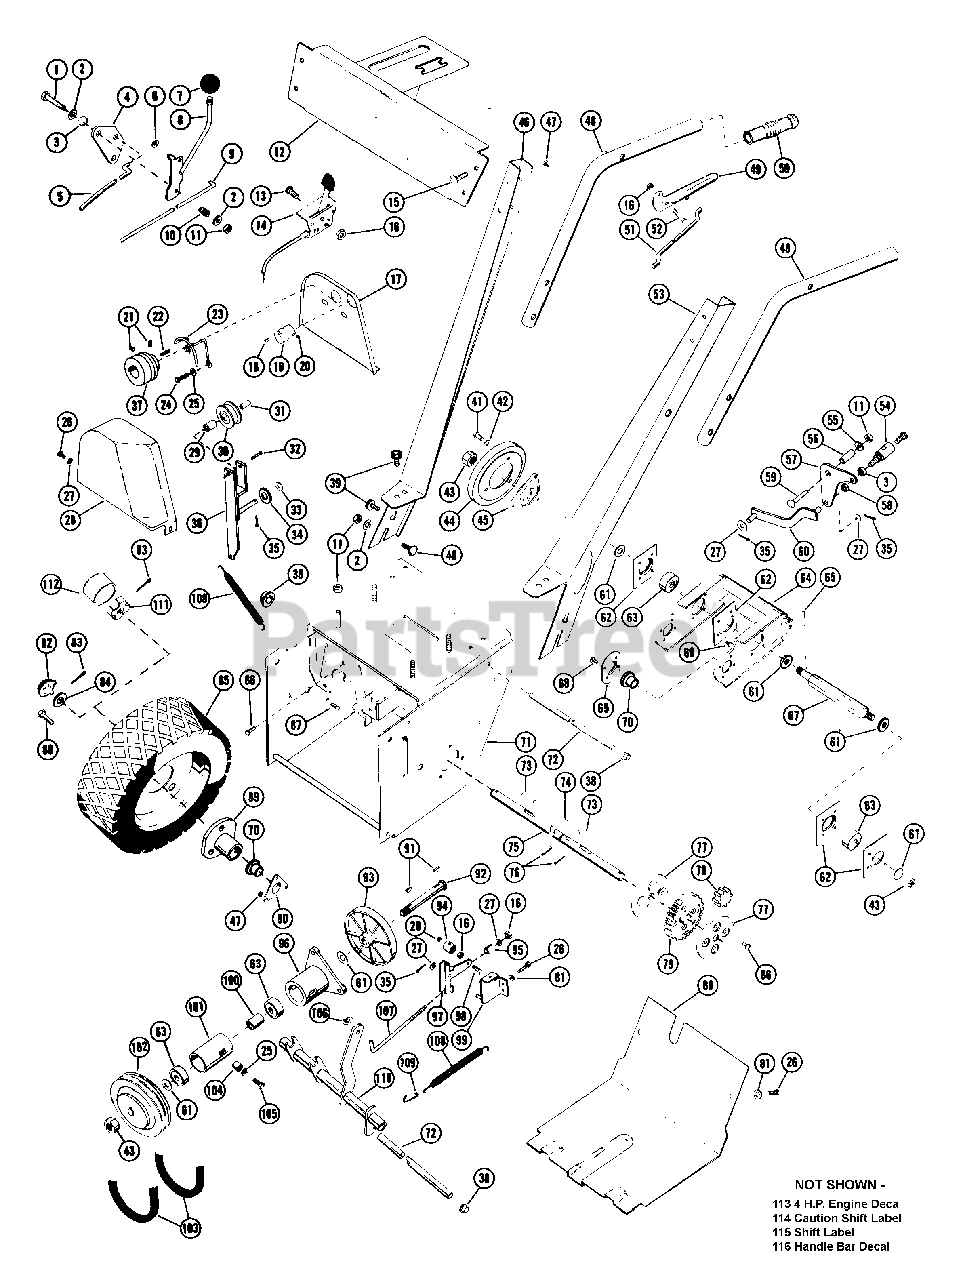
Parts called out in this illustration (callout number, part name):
1	BLT-HEX .31-18X1.75 PL GR2
2	WSHR-FL-STL.312X.734X.065PL
3	SPACER BUSHING .5 X .32 X .21
5	LOWER CLTCH ROD
6	SPRINGGRIP FASTENER
7	SHIFT BALL
8	SHIFT HANDLE
9	SHIFT ROD
10	SG-COMP .092X.375X2.53
11	NUT-LK .312-18 GR A PL
12	HNDLBR BRCKT
13	BLT-HEX .25-20X.75 PL GR2
14	THROTTLE CONTROL
15	BLT-RDHDSQNK .25-20X1.50 SHTPL
16	NUT-LK-CTR .250-20 PL
17	INNER BELT COVER
18	KEY-WDRF .125X.625X.250 SAE5
19	CAMSHAFT SHEAVE
20	SCR-SET .25-20X.25 SKHCUPNY OH
21	SCR-SET .32-18X.38 SKHCUPNL OH
22	KEY-SQ .188X1.0X.188 SAE 8630
23	BELT FINGER
24	BLT-HEX .31-24X.75 PL GR5
25	WSHR-LK .312X.097 PL HVY
26	BLT-HEX .25-20X.50 PL GR2
27	WSHR-FL-STL .250X.562X.049 PL
28	OUTER BELT COVER
29	BSHG-SLV .500X.625X.937
31	IDLER SHAFT
32	RVT-TBLR .187X1.343 OH ST YZWC
33	WSHR-FL-STL .268X.562X.046 PL
34	WSHR-FL-STL .281X1.250X.048PL
35	PIN-COTR .09X.75 PL
36	IDLER ARM
37	ENGINE SHEAVE
38	CAP, .50 ROD YWZC
39	BLT-SERHFWH .31-18X.50 PL
40	BLT-RDHDSQSHNK .31-18X.50 YZ
41	BLT-HEX .25-20X.38 PL GR2
42	WSHR-LK-EXT. 250 ID
43	NUT-LK-CTR .50-20 PL
44	FRICTION DISC
45	FRICTION DISC HUB
46	R H LOWER HANDLE BAR
47	NUT-LK-FLG .250-20 PL
48	HANDLE BARS
49	CLUTCH HANDLE
50	GRIP
51	UPPER CLTCH ROD
52	BLT-HEX .25-20X1.50 PL GR5
53	L H LOWER HANDLE BAR
54	BALL JOINT
55	WSHR-FL-STL .38X.875X.083 PL
56	BSHG-SLV .334 X .502 X 1.437
57	SHIFT LEVER
58	NUT-LK-CTR .312-24 PL
59	BLT-RDHDSQNK .31-18X2.0 SHT PL
60	SHIFT LINK
61	WSHR-FL-STL .505X1.000X.062
62	BEARING RETAINER
63	BRG-BALL .500X1.38X.437
64	CARRIER
65	PIN-ROLL .188X1.00
66	RVT-POP .187X.402 DOME ST
67	HEX SHAFT
68	RVT-POP.125 X .294 DOME
69	BEARING RETAINER
70	BSHG-FLG .750X1.000X.625X1.250
71	TRACTOR FRAME
73	KEY-FTHR .188X1.25X.187 SAE
74	KEY-WDRF .25X.750X.313 SAE91
75	AXLE SHAFT
76	PIN-ROLL .125X1.00
77	RETAINER PLATE
79	SPUR GEAR, FELLOWS 35T .750 ID
81	WSHR-LK .250X.077 HVY PL
82	HUB CAP
83	PIN-COTR .12 X 1.25 PL
84	WSHR-FL-STL .755X2.000X.125
85	WHL 10.25 IN O.D.
86	SCR-TAP .312-18X.50 CRPH PL 1A
87	SCR-SLTR-SERNK .25-20X.62 PL
88	BLT-WHL .50-20X.50 GR5 PL
89	WHEEL HUB
90	SUPPORT, BEARING
91	KEY-WDRF .125X.500X.203 SAE 3
92	SPINDLE
93	DRIVE DISK
94	ROD ADAPTER
96	DRIVE SPINDLE HOUSING
97	DEADMAN LEVER
98	BLT-HEX .25-20X.75 PL GR5
99	DEADMAN BRACKET
100	BEARING SPACER .75 X .5 X.88
101	SPINDLE HOUSING
102	DRIVE SHEAVE
103	V-BELT, SPECIAL-RAW EDGE (SET)
105	BLT-HEX .31-18X1.00 PL GR 2
106	RATCHET PLATE
107	ADJUSTMENT LINK
108	SG-TENS .063X.44X2.81 WLD 18
109	SPRING HOOK
111	SPINDLE CUP
112	HUB CAP
